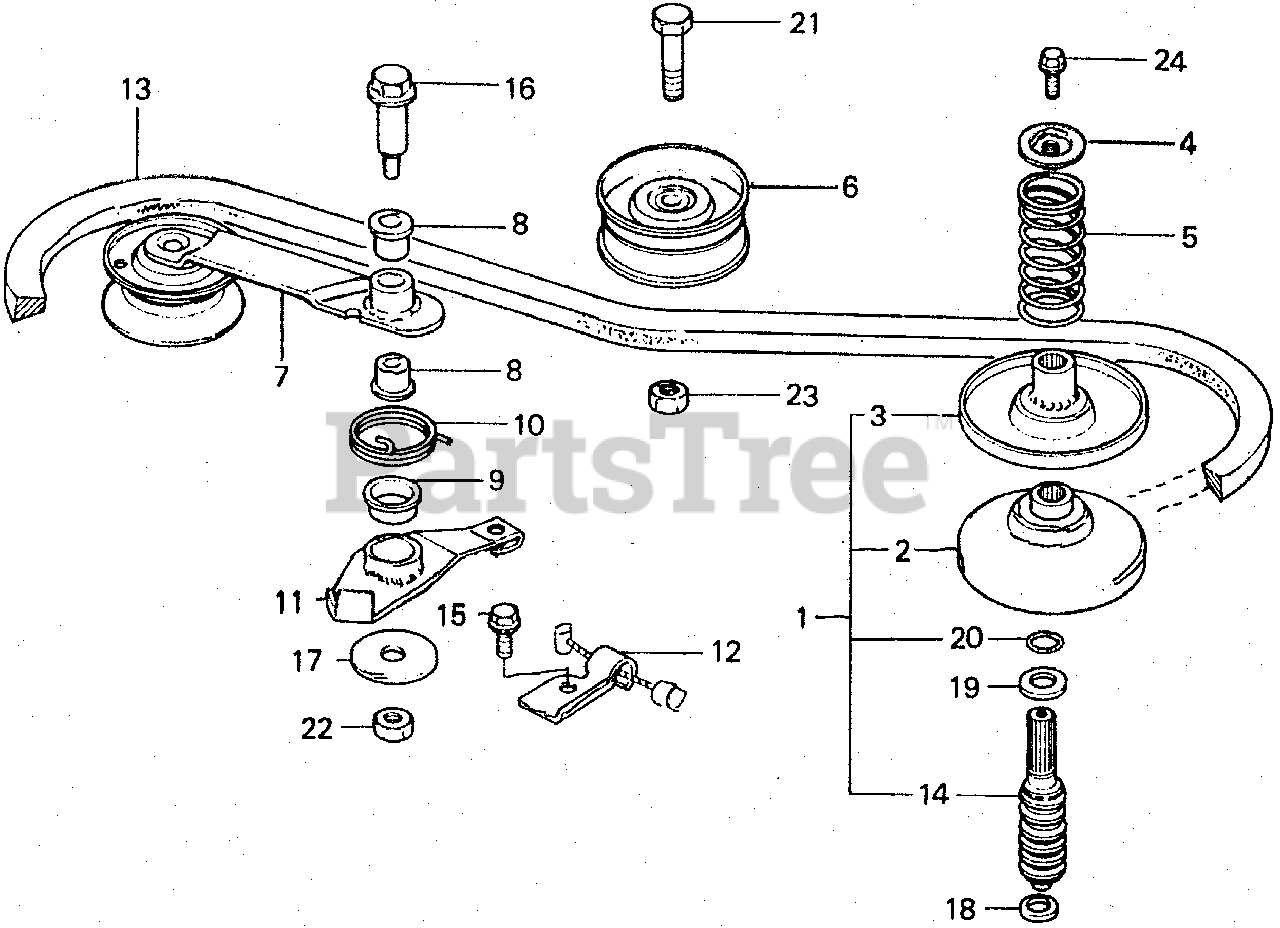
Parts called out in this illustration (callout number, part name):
1	PULLEY KIT, DRIVE
2	FACE, DRIVEN
3	FACE, MOVABLE DRIVEN (NOT AVAILABLE)
4	SEAT, SPRING (NOT AVAILABLE)
5	SPRING, DRIVEN FACE (NOT AVAILABLE)
6	ROLLER
7	ARM, TENSIONER (NOT AVAILABLE)
8	BUSH, TENSIONER ARM (NOT AVAILABLE)
9	BUSH, CHANGE ARM
10	SPRING, TENSIONER ARM (NOT AVAILABLE)
11	ARM, CHANGE (NOT AVAILABLE)
12	HOLD, CHANGE WIRE
13	V-BELT (35)
14	GEAR, DRIVE
15	BOLT, FLANGE (6X12) (CT200)
16	BOLT, TENSIONER ARM
17	WASHER, PLAIN (8MM) (NOT AVAILABLE)
18	WASHER (8MM) (NOT AVAILABLE)
19	WASHER, THRUST (12MM)
20	O-RING (11.7X1.2) (NOT AVAILABLE)
21	BOLT, HEX. (10X28)
22	NUT, HEX. (8MM)
23	NUT, HEX. (10MM)
24	BOLT, FLANGE (6X12) Use up to Engine SN 1543277.
